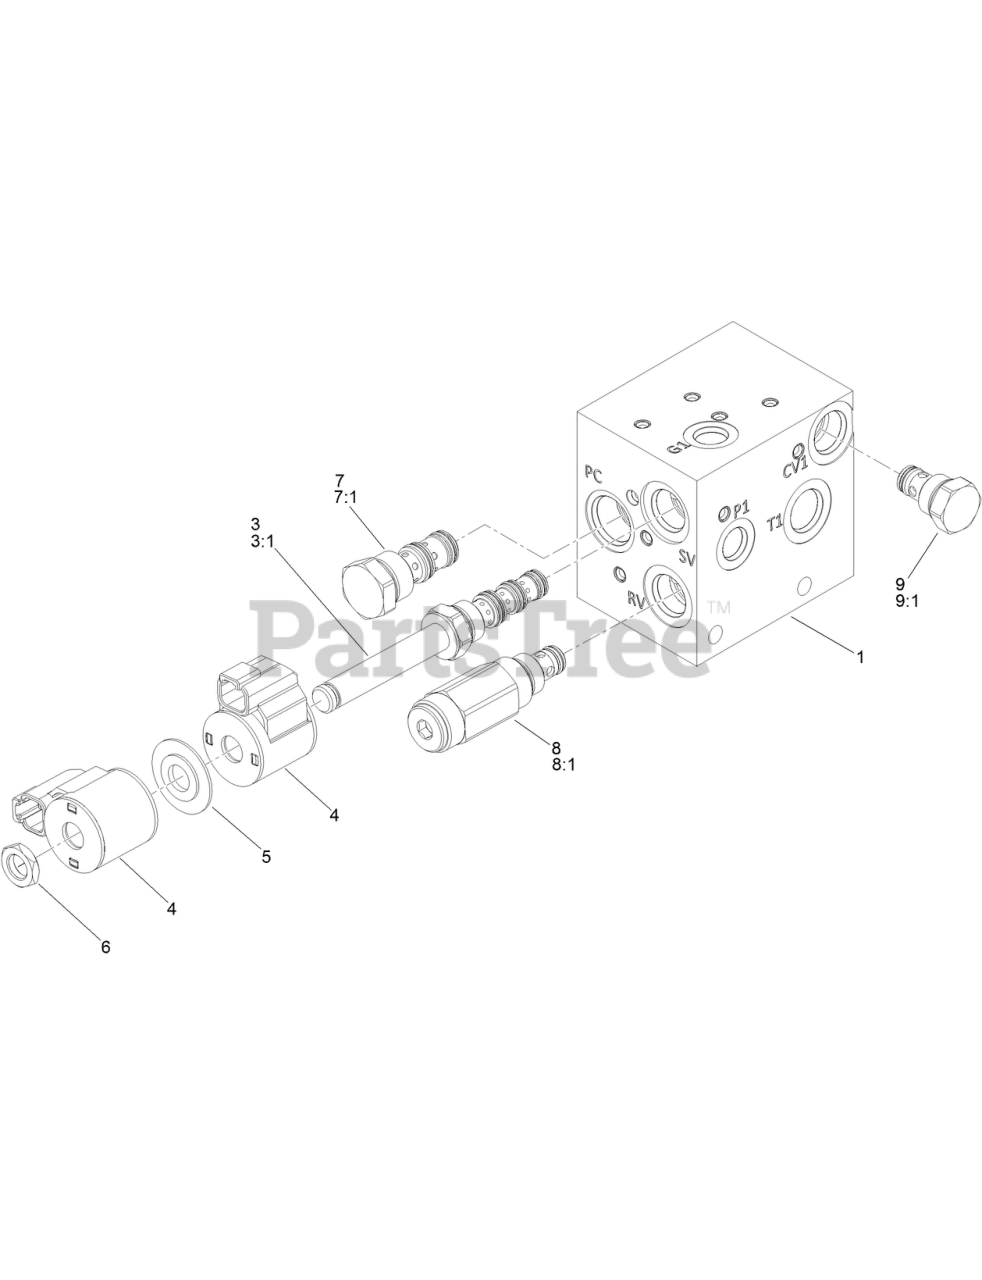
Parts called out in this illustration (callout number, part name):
1	Block-Manifold
3	Valve-Solenoid
3:1	Seal Kit
5	Spacer-Coil
6	NUT-COIL
7	VALVE-CHECK, P O
7:1	SEAL KIT
8	Check Valve ASM
8:1	SEAL KIT
9	Valve-Relief, 900PSI
9:1	Seal Kit
